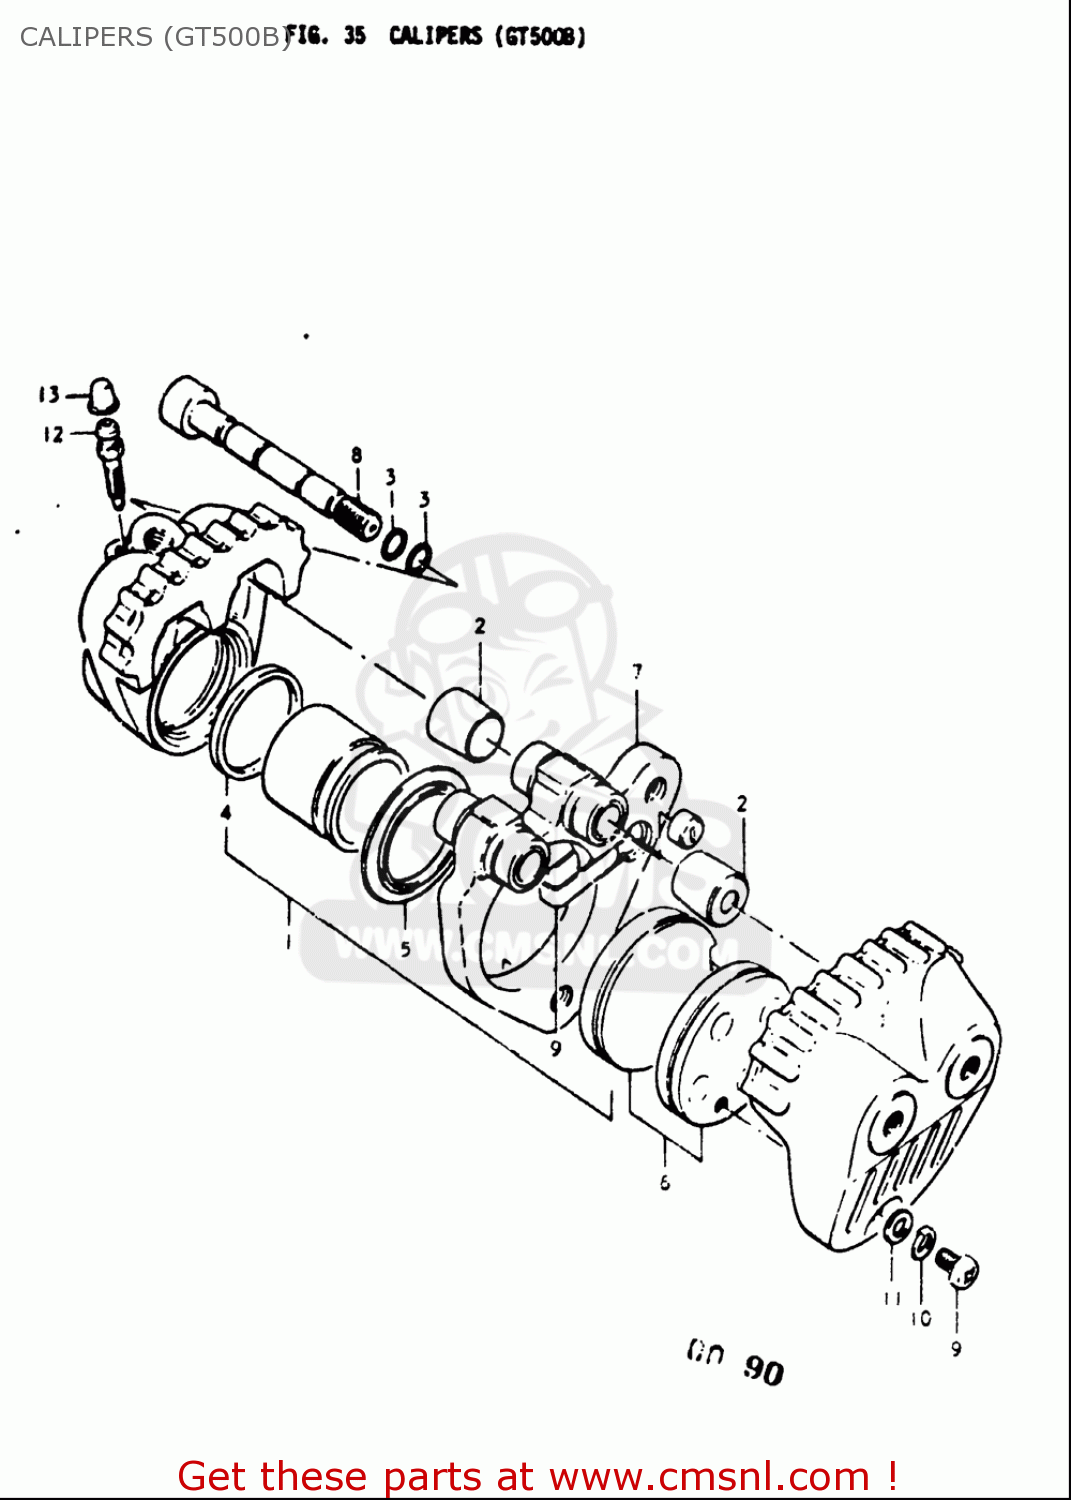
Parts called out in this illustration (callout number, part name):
2	BOOT,HOLDER
3	O RING,AXLE CALIPER
4	SEAL,PISTON
5	BOOT,PISTON
7	HOLDER,CALIPER
8	AXLE,CALIPER
9	SCREW
10	WASHER,LOCK
11	WASHER
12	BLEEDER
13	CAP,BLEEDER PLUG
